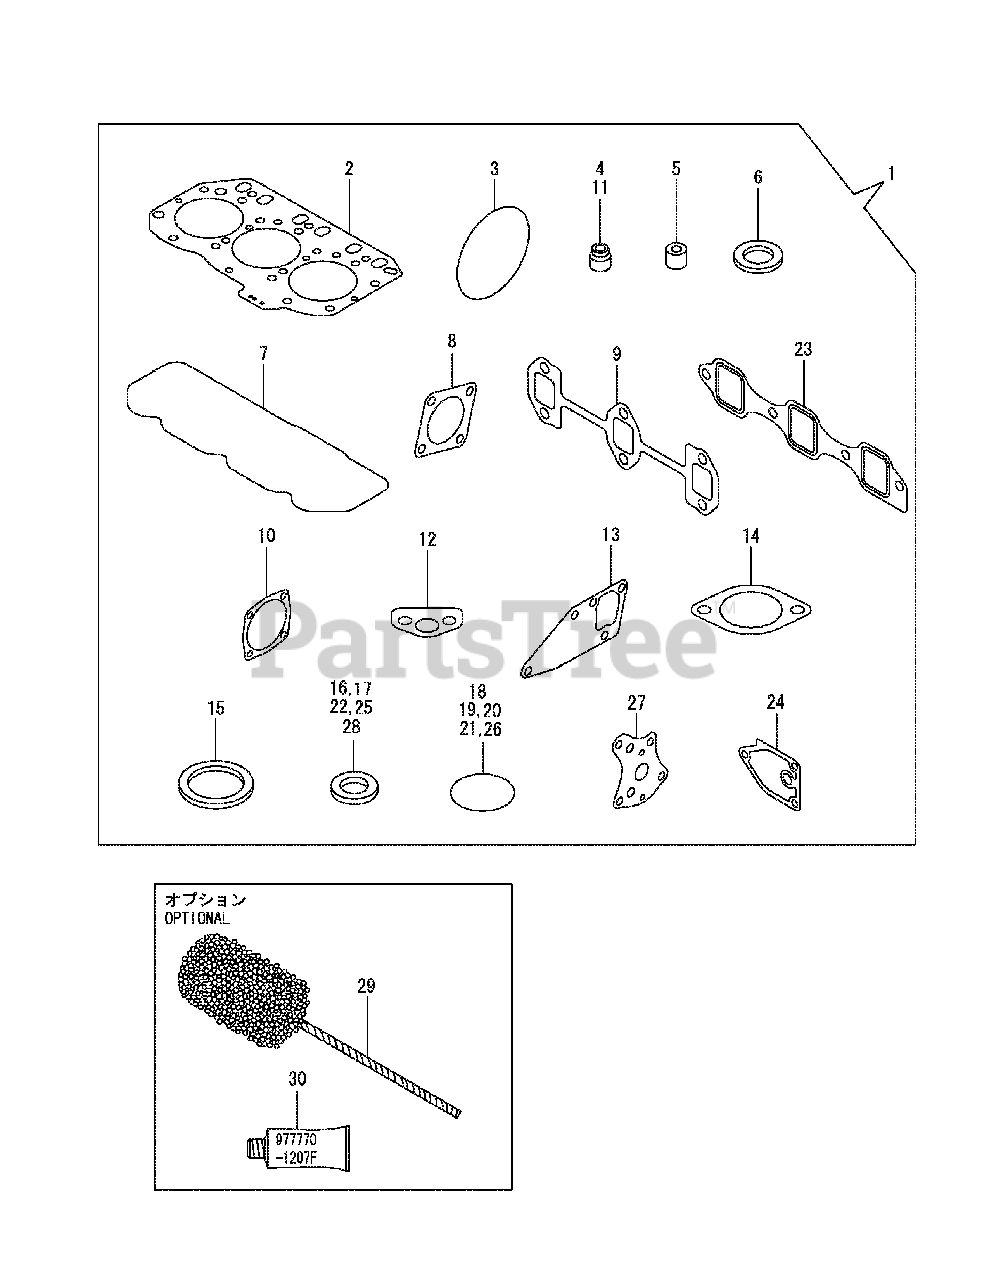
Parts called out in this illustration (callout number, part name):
1	Complete Packing Set
3	Pump O-Ring, F.I.
4	Valve Stem Seal
5	Nozzle Protector
9	Exhaust Manifold Gasket
11	Valve Stem Seal
13	Water Pump Gasket
15	Thermostat Gasket
16	Round Gasket, 8
17	Seal Washer, 8S
18	O-Ring, 4D P-10A
19	O-Ring, 1A P-12.0
20	O-Ring, 1A P-32.0
21	O-Ring, 1A S-24.0
23	Manifold Gasket
29	Flex Horn
30	Liquid Gasket
